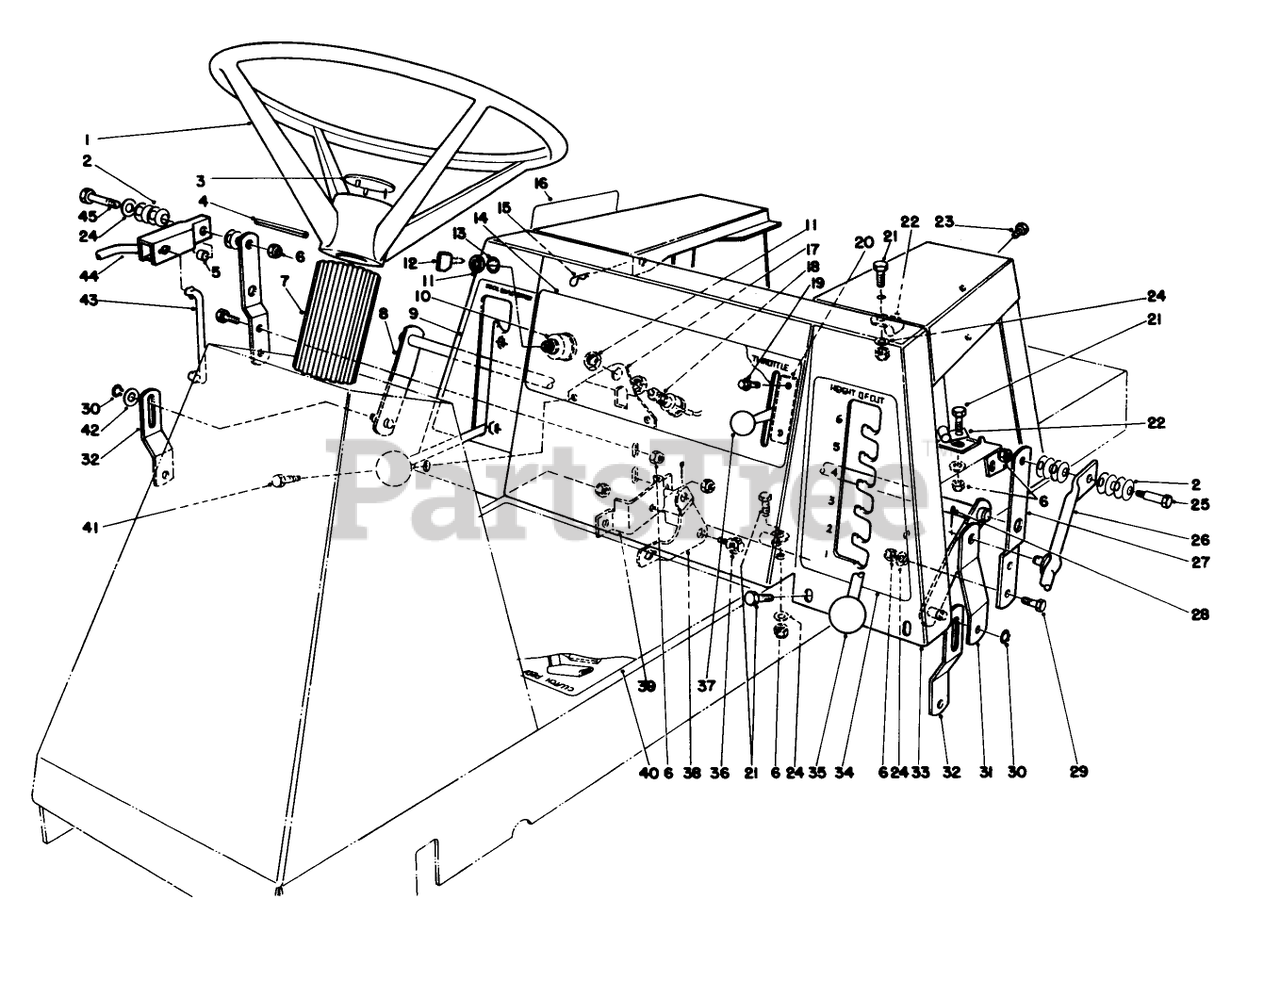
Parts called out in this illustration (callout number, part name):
1	STEERING WHEEL ASM
2	Belleville Washer
3	INSERT-STEERING WHEEL, TORO
4	PIN-ROLL
5	Spacer-Pivot
6	NUT-LOCK, NI
7	COVER-STEERING SHAFT
11	NUT-HH
12	KEY-IGNITION
13	WASHER-LOCK
17	SWITCH MT BRKT
18	DECK SWITCH
19	SCREW-HWHTF
20	THROTTLE CONTROL
21	SCREW-HH
22	CLAMP
23	SCREW-HH
24	WASHER-PLAIN
25	BOLT-SHOULDER
26	HOC LEVER WA *B
28	PIN-COTTER
29	SCREW-HH
30	RING-RETAINING
34	HOC DECAL
36	SCREW-SHOULDER
38	DECK ENGAGE BELLCRANK
41	SCREW-HH
42	WASHER-FLAT
43	BELLCRANK LINK(PLTD)
44	SHIFT LEVER WA *B
45	SCREW-HH
